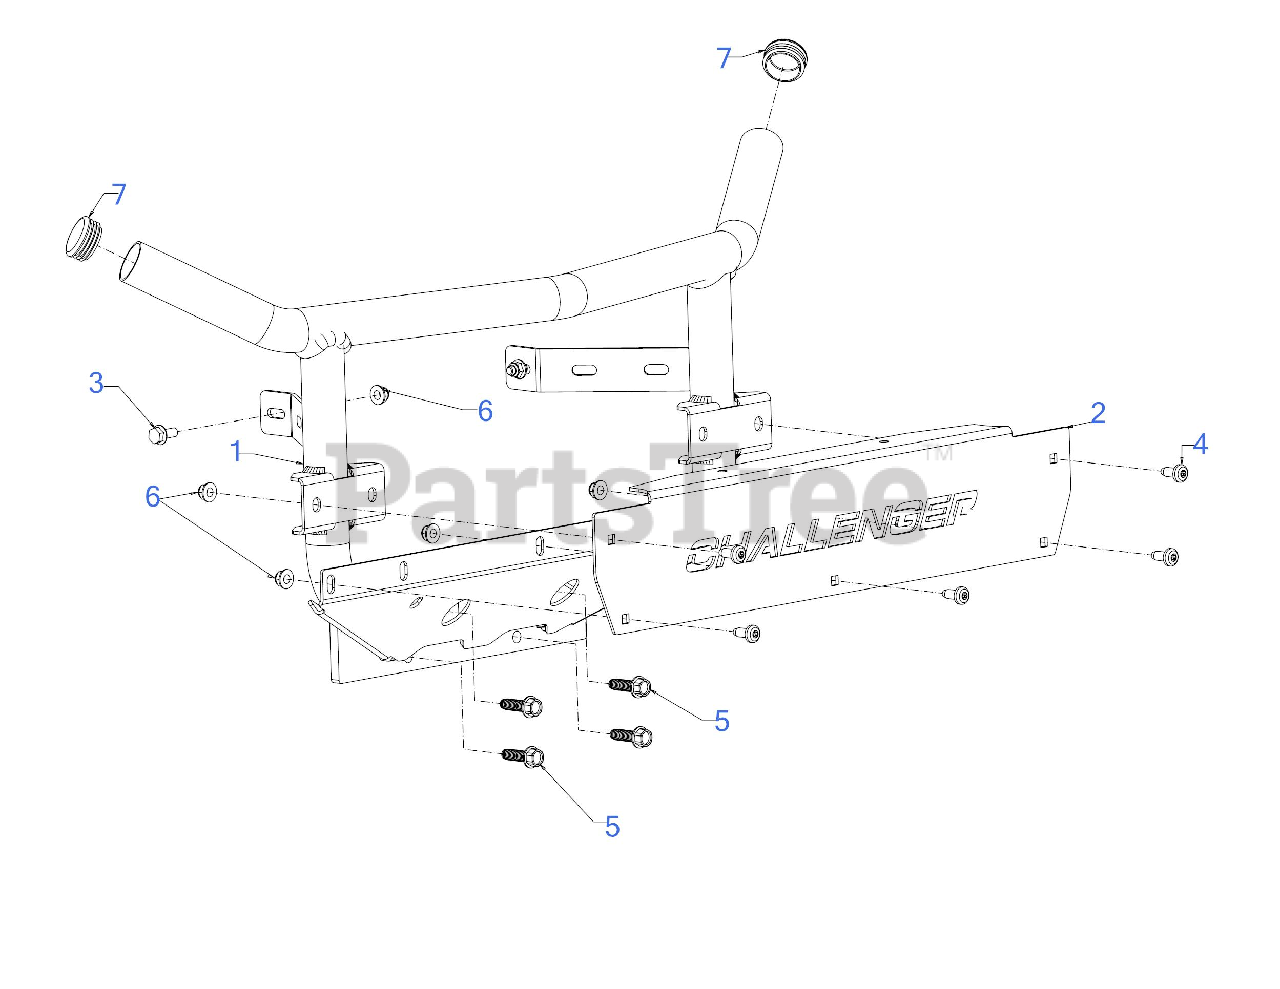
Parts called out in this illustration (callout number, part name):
3	SCREW 5/16-18
4	SCREW 5/16-18 X.75
5	SCREW 3/8-16 X1.250
6	FLANGE LOCK NUT 5/16-18
7	BUMPER CAP
